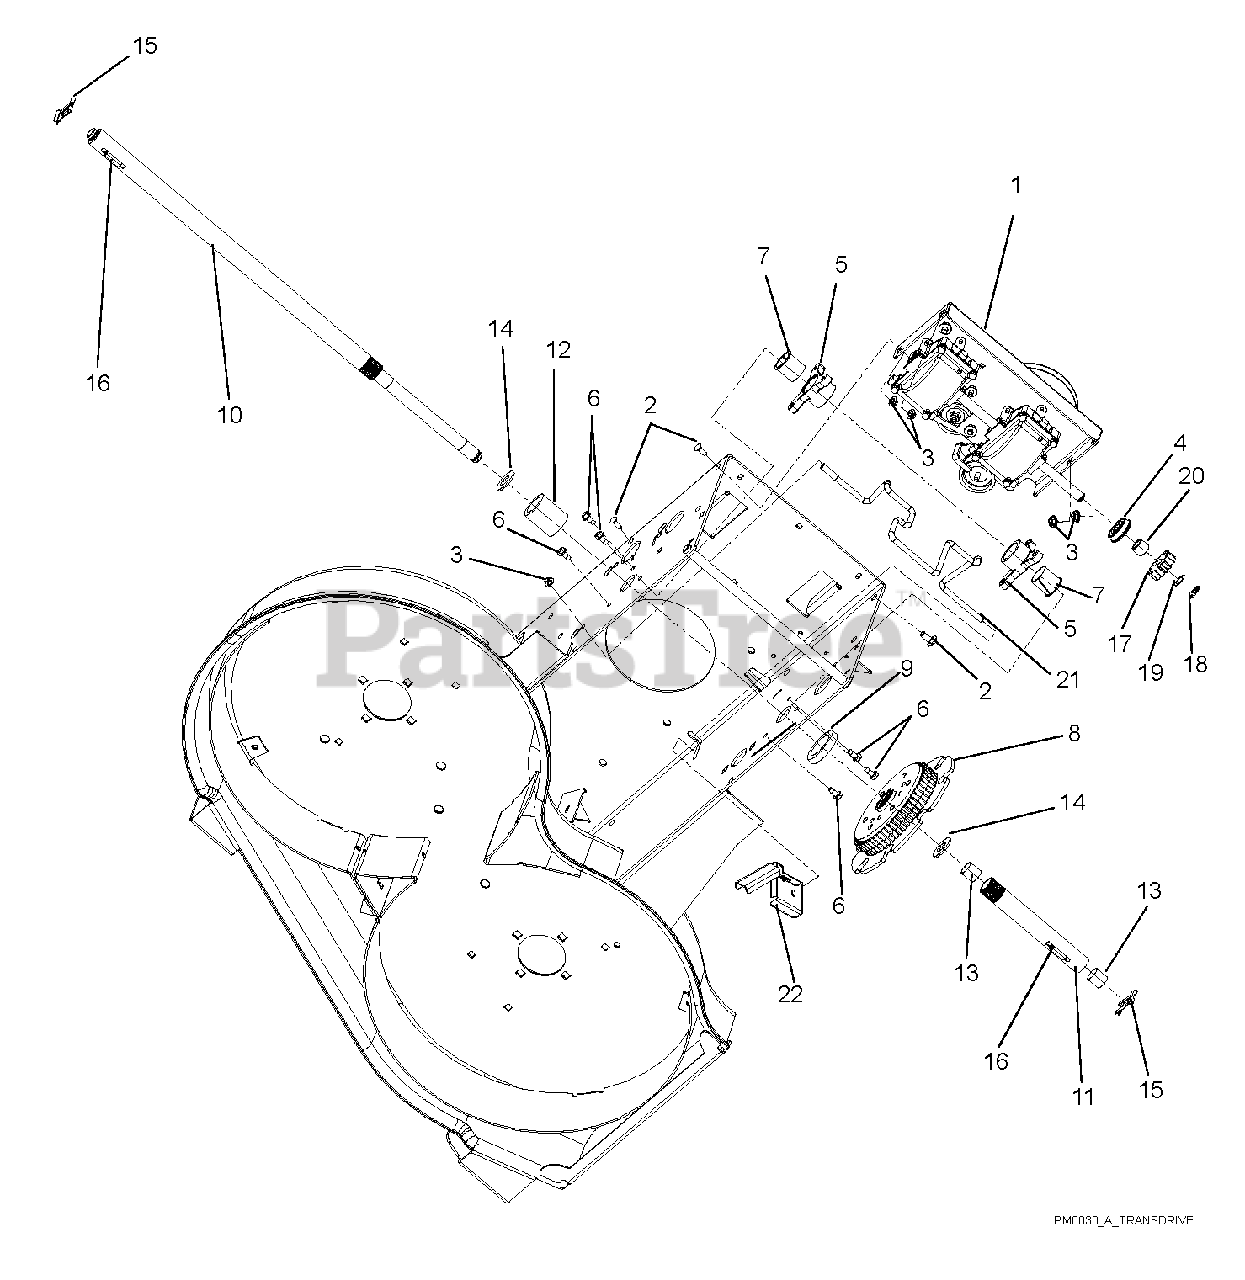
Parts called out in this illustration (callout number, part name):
1	Kit, WAW Transmission
2	Bolt, Round Head, Square Neck .31-18 x .75
3	Nut, Locking Top Flange .31-18
4	Bearing, Sealed Ball .50 1.38 x .438
5	Bushing, Rake Shaft 1"
6	Screw, Tapping Hex Washer Head .25-20 x .50
7	Bushing, Flange Split 1.0"
8	Kit, Differential
9	Washer, Flat Nylon 1.42 x 2.03 x .35
10	Shaft, Axle Long
11	Shaft, Axle Short
12	Spacer 1.0 x 1.5 x 1.57
13	Bushing, Sleeve .706 x .764 x .75
14	Washer, Flat Steel 1.0 x 1.50 x .062
15	Clip, Snap .625 Diameter
16	Key, Rectifier .25 x .188 x 1.00
17	Pinion, Transmission Drive
18	Ring, External Retaining .500 x .042
19	Washer, Thrust .500 x .020
20	Retainer, Bearing
21	Belt Finger
22	Guide, Vertical Belt
